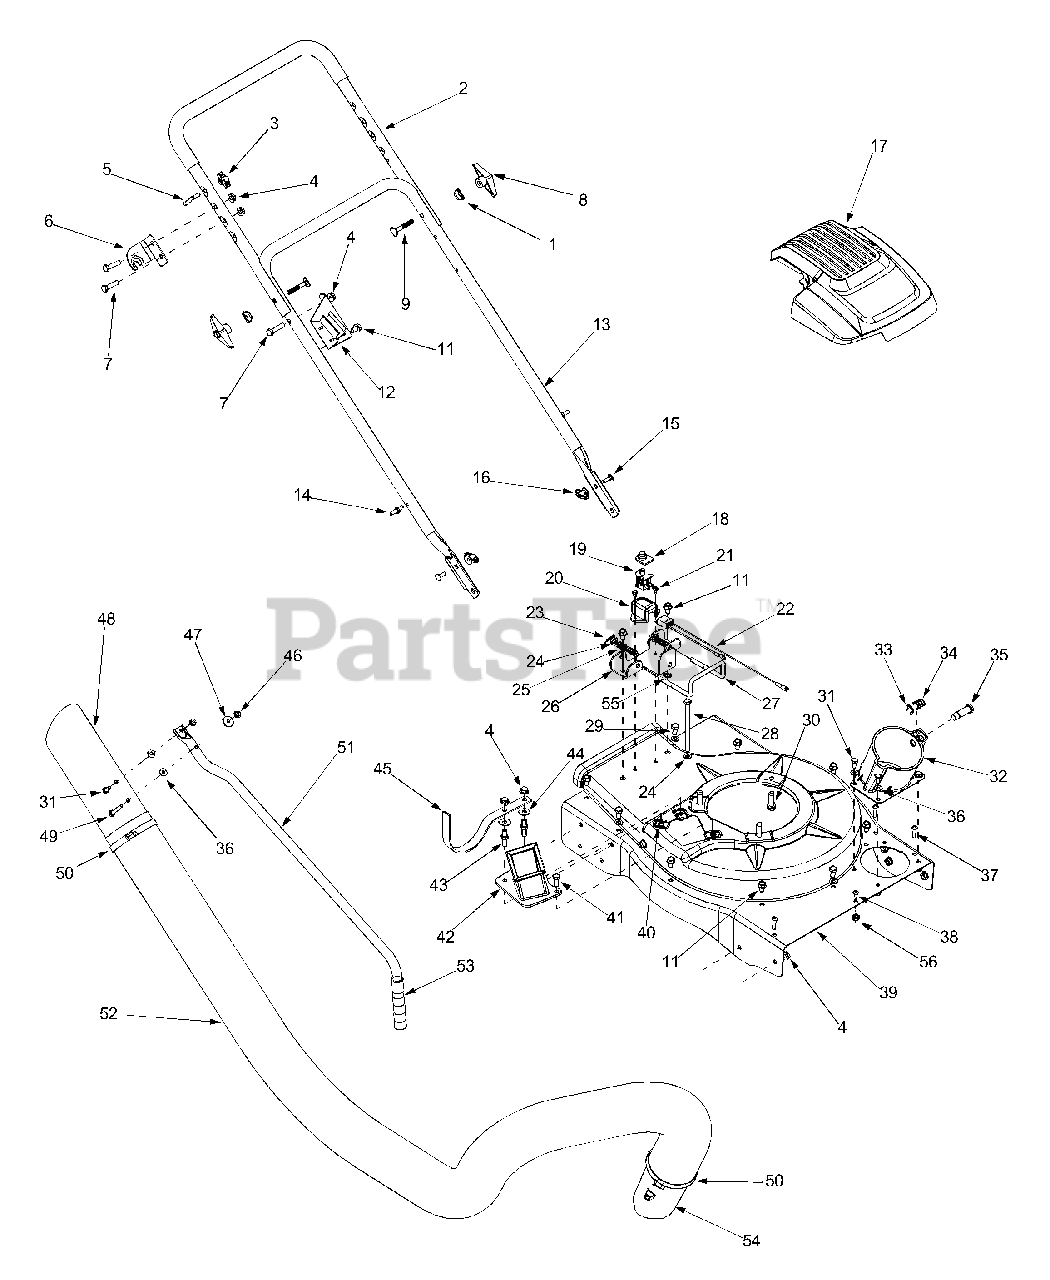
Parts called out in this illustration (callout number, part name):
1	Saddle Washer, .320 x .93
4	Flange Lock Nut 5/16-18
5	Eye Bolt
7	Hex Cap Screw 5/16-18 x 1.25
8	Handle Knob 5/16-18
9	Carriage Bolt
11	Hex Washer Screw 5/16-18 x.625
12	Lower Handle Bracket
14	Studs
15	Carriage Screw 1/4-20 x.75
16	Wing Nut 1/4-20
18	Switch Cover
19	Safety Switch
20	Safety Switch Cover
21	Hex Washer Screw #10-16 x.50
22	Wire Harness
23	Cotter Pin
24	Flat Washer .330 ID x.630 OD
25	Compression Spring
27	Lock Rod
28	Hex Cap Screw 5/16-18 x 4.5
29	Hex Cap Screw 5/16-18 x.625
30	Hex Washer Screw 3/8-16 x 1.25
31	Hex Cap Screw 1/4-20 x .620
32	Hose Base Adapter
33	E Ring .500 Dia
34	Compression Spring
35	Clevis Pin
36	Flat Washer .271 ID x .630 OD
37	Screw #12-16 x 1.0
38	Machine Screw #10 - 24 x .625
40	U-Clip Lock Nut 5/16-18
41	Hex Cap Screw 5/16-18 x.75
43	Stud 5/16-18 x .56
44	Flat Washer .343 ID x .880 OD
47	Spacer
48	Hose Nozzle
49	Hex Cap Screw 1/4-20 x 2.625
50	Adjustment Clamp
52	Vacuum Hose
53	Handle Grip
54	Hose Adapter
55	External L-Washer 5/16
56	Hex Lock Nut #10 - 24
